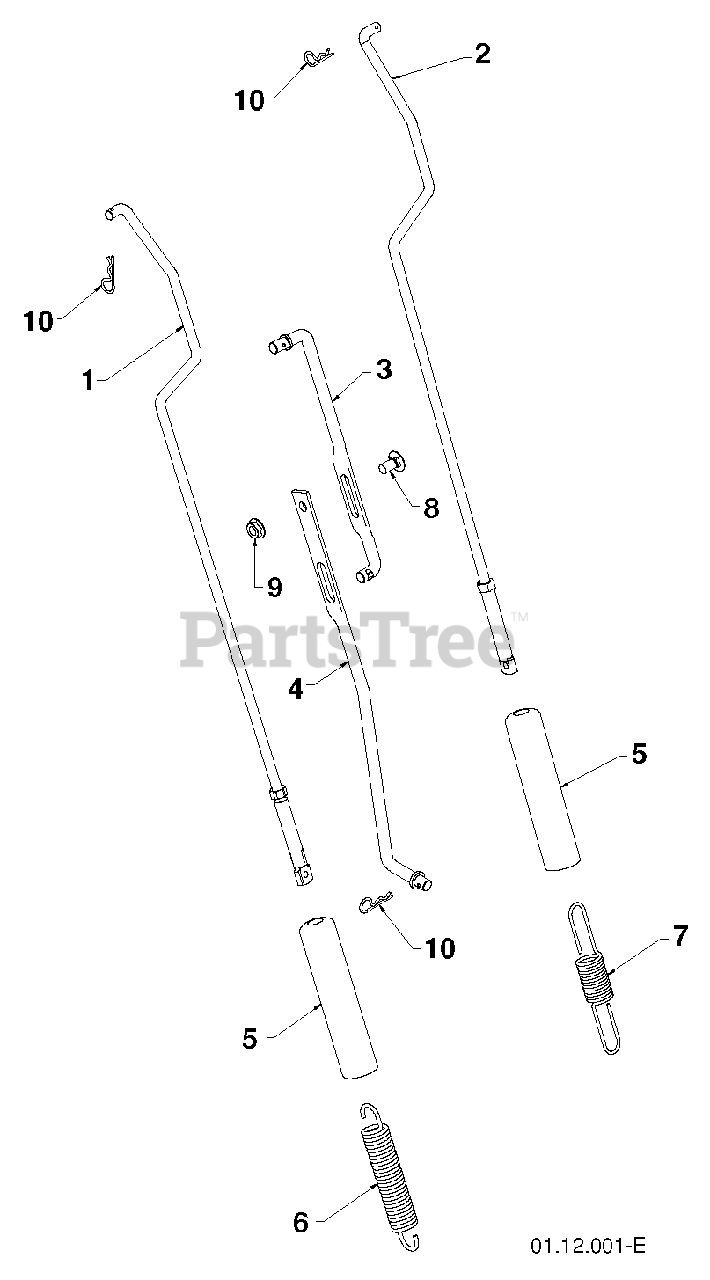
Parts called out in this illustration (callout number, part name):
1	ROD.IMPELLER.CONTROL.SNOW
2	ROD.TRACTION.CONTROL.SNOW
3	ROD, UPPER SPEED CONTROL
4	ROD, LOWER SPEED CONTROL.SNOW
5	SLEEVE, SPRING
6	SPRING.CONTROL.ROD.SNOW
7	SPRING.TRACTION.ROD.SNOW
8	BOLT
9	NUT.FLANGE.5/16
10	SPRING RETAINER
